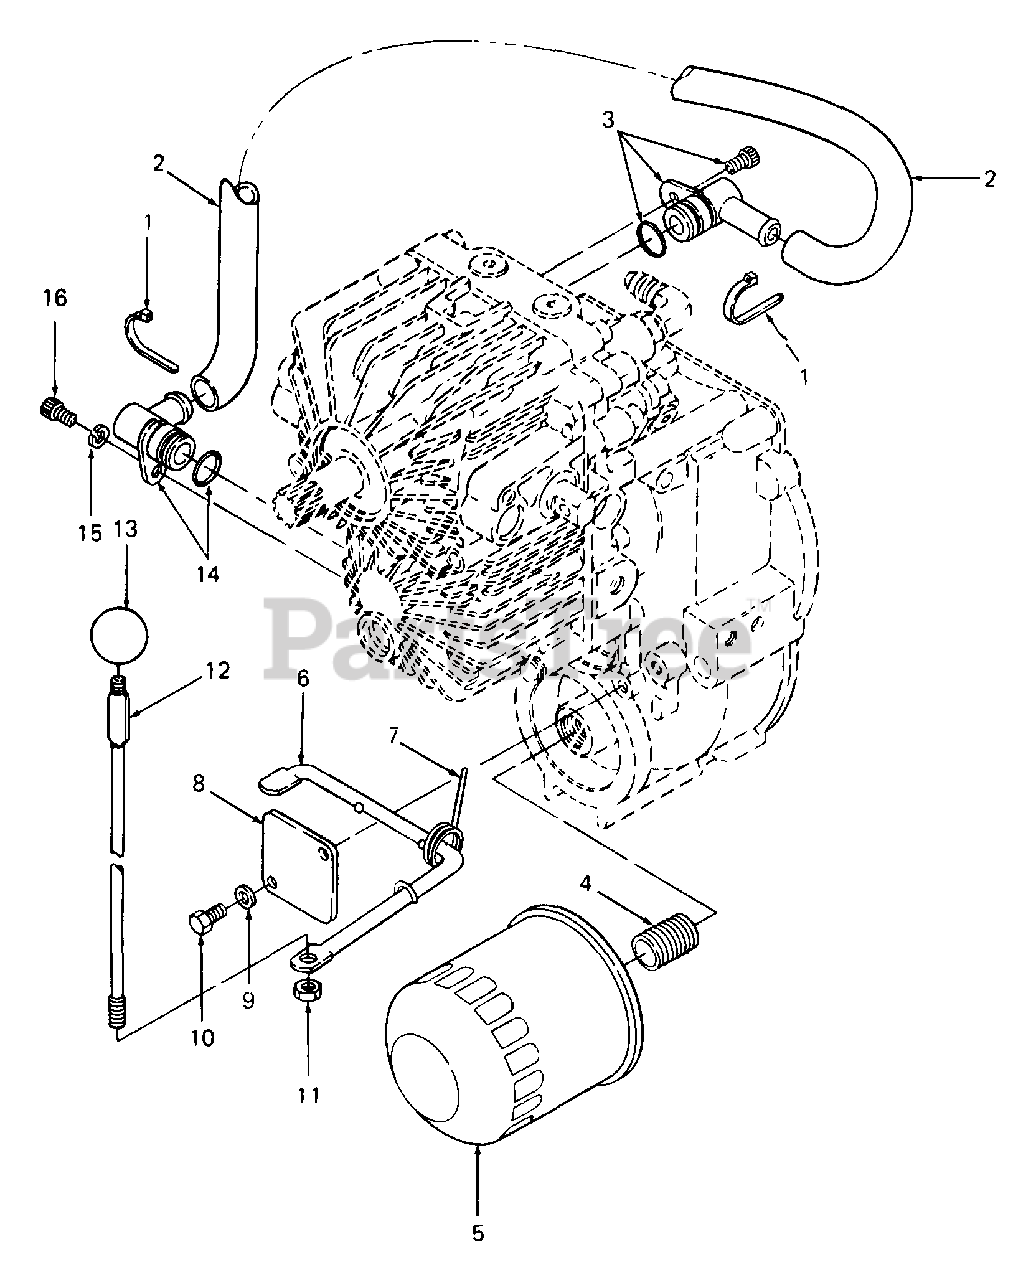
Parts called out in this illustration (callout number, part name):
1	Cable Tie
2	Line, Pickup
3	Fitting Assembly
4	Nipple, Oil Filter
5	Filter, Oil
6	Rod, Dump Valve Lower
7	Spring, Torsion
8	Plate, Retaining
9	Washer, Lock, 1/4
10	Screw, Hex Cap, 1/4-20 x .50 Lg GR5
11	Nut, Hex Top Lock, 1/4-20
12	Rod, Dump Valve Upper
13	Knob, Ball
14	Fitting Assembly
15	Washer, Lock, 1/4
16	Screw, Socket Head, 1/4-20 x .65 Lg
